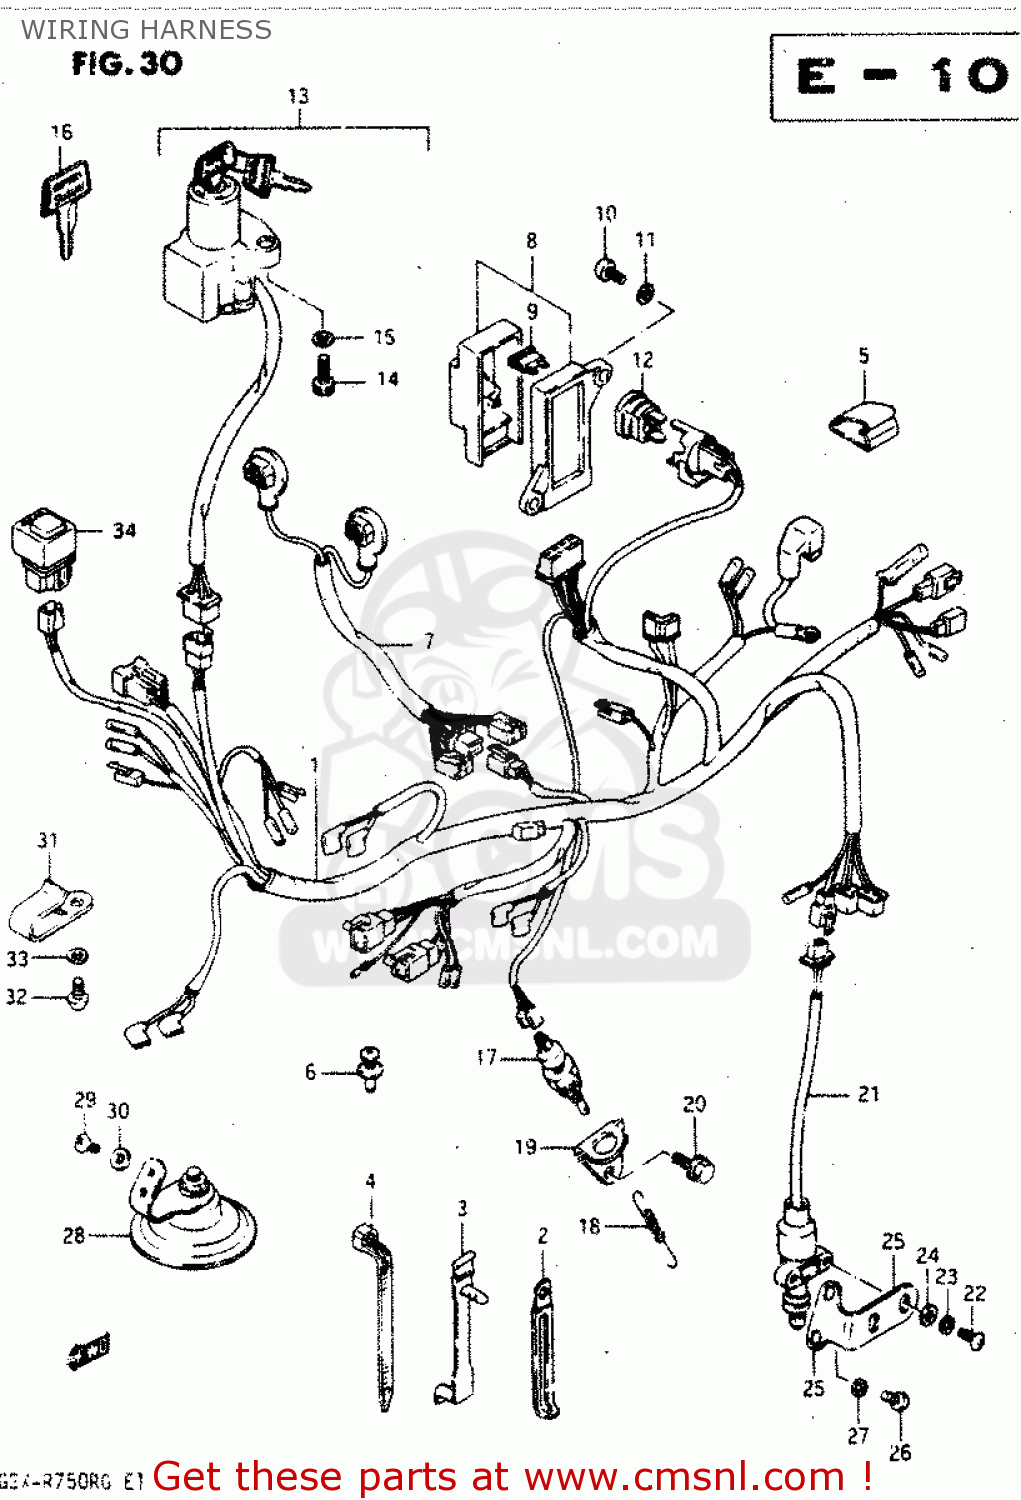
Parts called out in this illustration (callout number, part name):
1	HARNESS,WIRING
2	CLAMP
3	CLAMP(L:55)
4	CLAMP
5	CLIP
6	CLIP
7	WIRE, HEADLAMP LEAD
8	BOX ASSEMBLY,FUSE
9	FUSE(10A)
10	SCREW 6X12
11	WASHER
12	BREAKER ASSY,CIRCUT
13	SWITCH ASSY,IGNITION
14	BOLT
15	WASHER,LOCK
16	KEY,BLANK
17	SWITCH ASSY,STOP LAMP
18	SPRING
19	BRACKET,STOP LAMP SWITCH
20	BOLT (6X20)
21	SWITCH ASSY,SIDE STAND WARN
22	SCREW 5X20
23	WASHER,LOCK
24	WASHER,5MM
25	BRACKET,PROP STAND WARNING
26	SCREW 6X12
27	WASHER,LOCK
28	HORN ASSY
29	SCREW
30	WASHER
31	CLAMP,HANDLE SWITCH LEVER
32	SCREW
33	WASHER,LOCK
34	RELAY, ANTINOSE DIVE FORK
